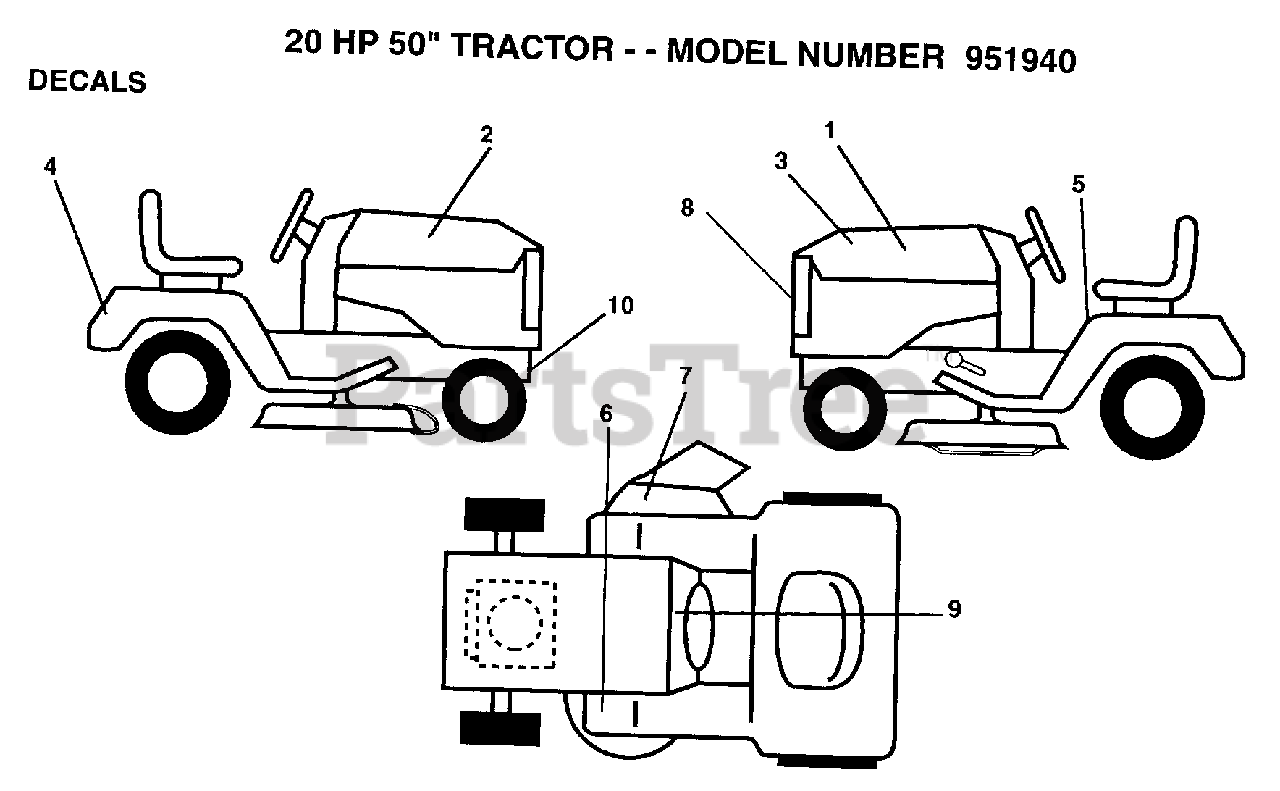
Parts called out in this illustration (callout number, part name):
1	DECAL HOOD LH
3	DECAL.PANEL.SIDE
5	DECAL
7	DECAL WARING
8	DECAL.GRILL.YARDP
